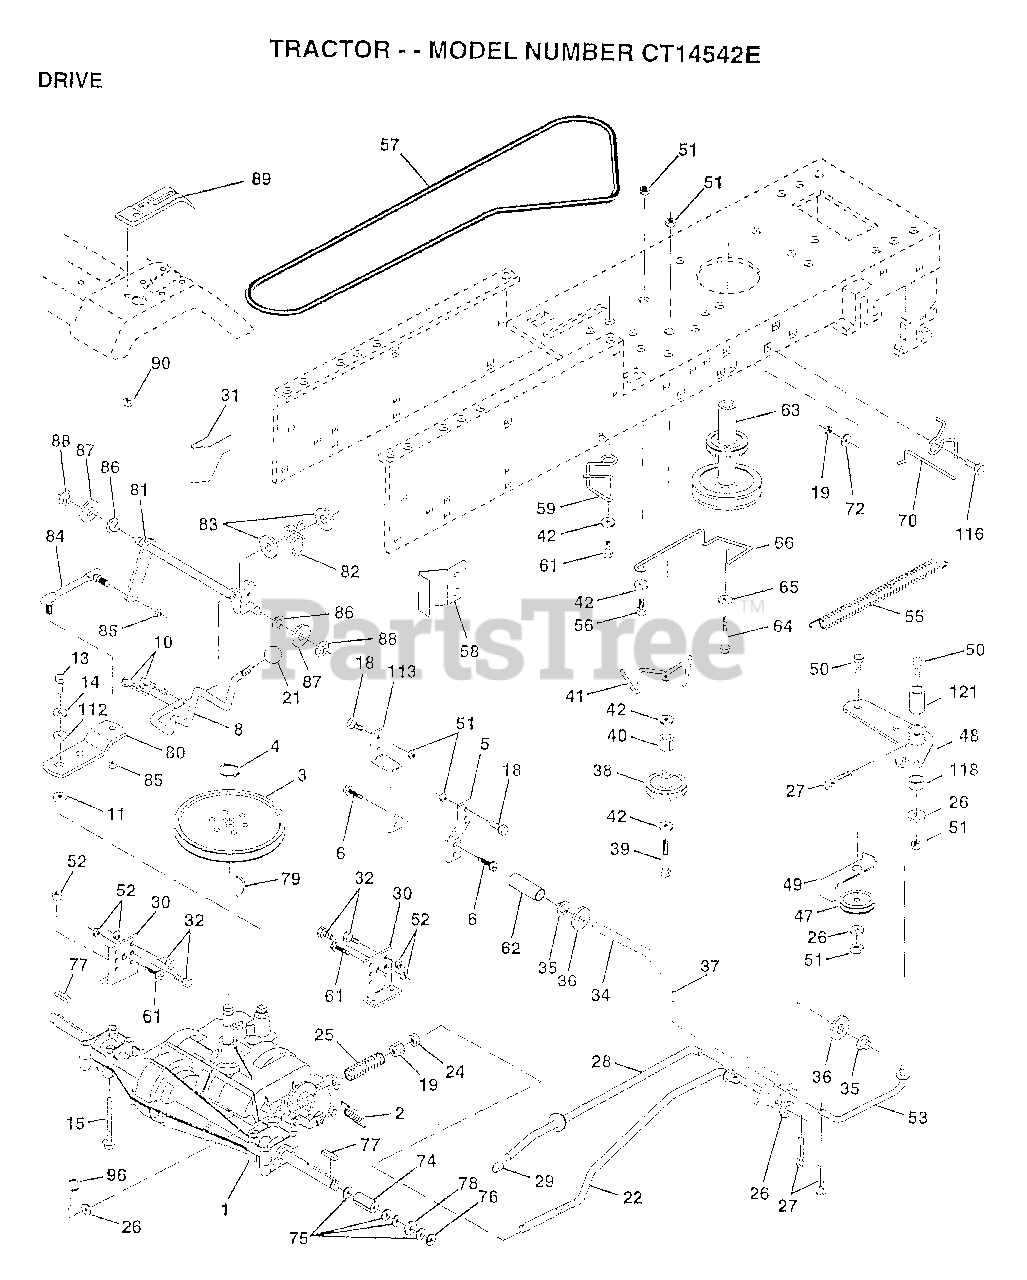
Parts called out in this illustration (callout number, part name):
1	TRANSAXLE PEERLESS
2	SPRING.BRAKE.RETU
3	PULLEY TRANS
5	STRAP TORQUE
6	SCREW
8	ROD SHIFT FEND LT
10	PIN COTTER 1/8
11	WASH-SHFT PLT LT
13	BOLT.1/4-28.W/PAT
14	LOCKWASHER
15	BOLT.HX.FLG.5/16
18	BOLT
19	NUT
21	KNOB T (1/2-HOLE)
22	BRAKE ROD
24	NUT
25	SPRING ROD LT
26	WASHER
27	COTTER PIN
28	ROD.BRAKE.PARK.LT
29	PLUNGER CAP T
30	TRANSAXLE MTG BKT
31	"KEEPER,BELT LH T"
32	BOLT
34	SHAFT ASM-PEDAL F
35	NYLON BEARING
36	WASHER LT
38	PULLEY.IDLER.FLAT
39	BOLT
40	SPACER T
42	WASHER
48	BELLCRANK ASM
49	RETAIN BELT
53	"LINK, CLUTCH T"
55	"SPRING, RETURN LT"
58	"KEEPER,BELT RH T"
59	KEEPER BELT CNTSP
61	SCREW
62	PEDAL COVER T
63	PULLEY.ENGINE
64	BOLT
65	LOCKWASHER
66	KEEPER-BELT
70	KEEPER BELT ENG
72	WASHER
74	SPACER, AXLE
75	WASHER
76	E-RING LT
77	SQUARE KEY
78	WASHER
80	"ARM.SHIFT.20""TIRE"
81	SHAFT.CROS.P930.
82	"SPRING,TORSION"
83	WASHER
84	"ROD.TIE.20""P930LT"
85	NUT.CNT.LOCK.1/4
86	BUSHING
87	WASHER D
88	KLIP RING
90	NUT
96	RETAINER M
112	WASHER LT
113	"STRAP,TORQUE"
116	BOLT RDHD 3/8-16
118	SPACER-BELLCRANK
121	NYLINER-CLUTCHING
